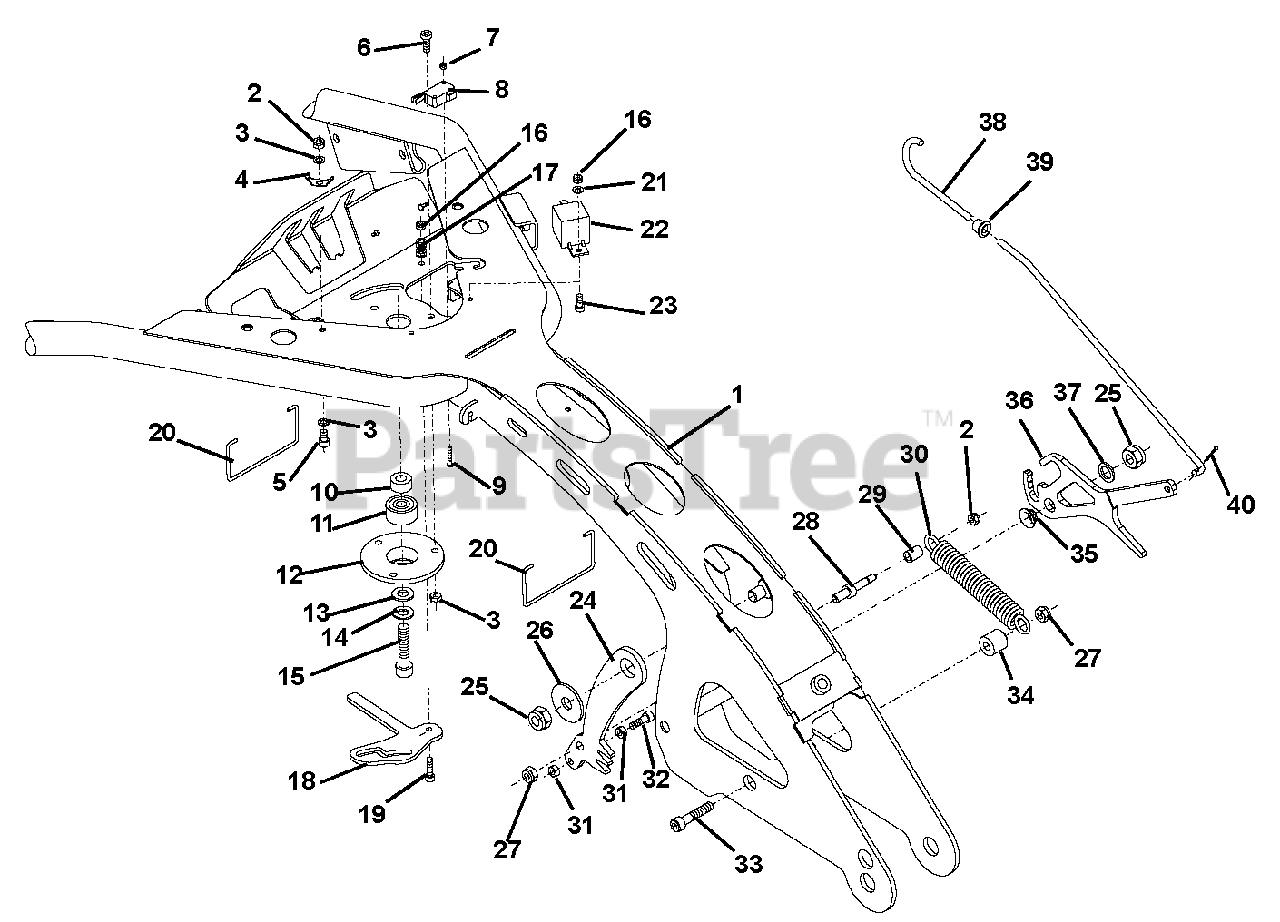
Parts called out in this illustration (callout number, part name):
2	Nut, Lock M6
3	Washer, Lock M6
4	Shell, Cable
5	Screw, M6 x 10
6	Screw, M6 x 16
7	Nut, Lock D985 M3
8	Switch
9	Screw, M3 x 18
11	Bearing, Ball
12	Bracket, Bearing
13	Washer, 10.5 x 21 x 2/2
14	Washer, 10.2/20.25 x 1.6
15	Screw, M10 x 45
16	Nut, Lock
17	Washer, Spring 10 x 5.2
18	Bar, Lock
19	Screw, M5 x 20
20	Cable Guide
21	Washer, 5.1/10.2 x 1.0
23	Screw, D912 M5 x 12
26	Washer, 13 x 40 x 3
27	Nut, Lock M8
28	Spring Retainer
29	Bushing, Distance
30	Spring, Tension 3.2/19.3 x 122
31	Nut, Hex M6
32	Screw, M6 x 20
33	Screw, M8 x 40A
34	Spring, Retainer
36	Rod, Shift
37	Washer, 13 x 20
38	Lever Adjustment, High Compression
40	Pin, Cotter
